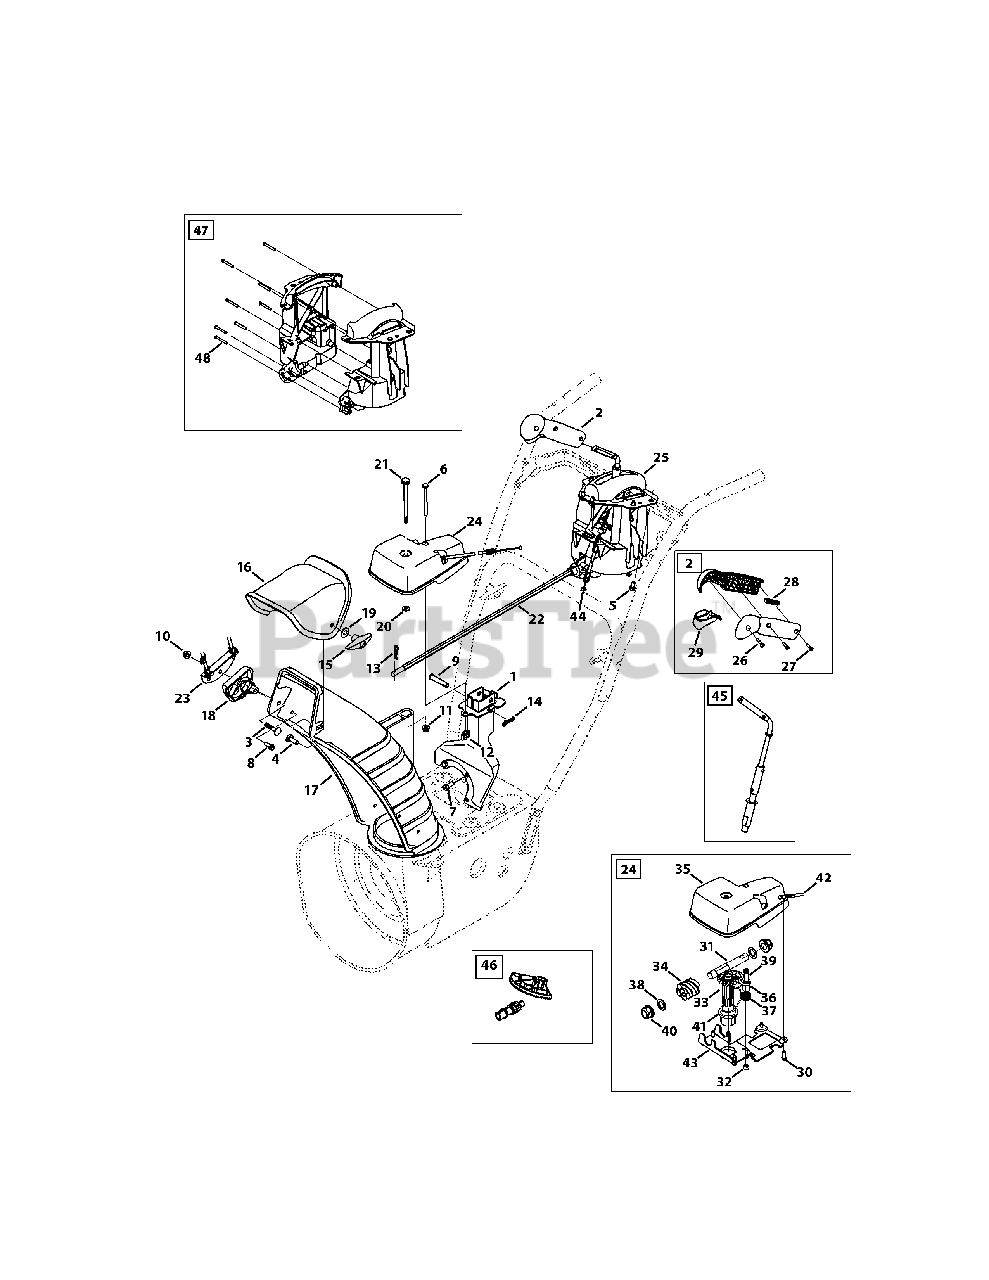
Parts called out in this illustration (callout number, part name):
1	Chute Support Bracket
2	Handle Assembly
3	Bolt, Carriage, 5/16-18 x 1.50
4	Bolt, Carrier, 5/16-18 x 1.00
5	Screw, HL, 1/4-15 x 0.50
6	Hex Head Screw, 1/4-20 x 3.00
7	Hex Head Screw, 5/16-24 x .750
8	Screw, HL, 1/4-15 x 0.750
9	Clevis Pin, 3/8 x 1.87
10	Nut, Flangelock, 5/16-18
11	Nut, Flangelock, 1/4-20
12	Wing Nut, 1/4-20
13	Internal Cotter Pin
14	Bow-Tie Cotter Pin
15	Star Knob, 5/16-18
16	Chute, Upper
17	Chute, Lower
18	Cable Guide, Chute Tilt
19	Washer, Flat, .349 x .879
20	Washer, Flat, .25 x .630
21	Screw, Shoulder, .312 x 3.5 x 1/4-20
22	Chute Rod, 3/8 Hex
23	Cable Bracket
24	Gearbox Assembly, Chute Rotation
25	Chute Control, 4-Way
26	Screw, #8 x 1.00
27	Screw, 8-32 x .750
28	Joystick Plug
29	Joystick Trigger
30	Screw, 12-16 x .75
31	Hex Shaft
32	Hexlock Nut, 1/4-28
33	Gear, 14 T
34	Worm
35	Gear Cover
36	Pawl Lock
37	Torsion Spring, .721 ID x .474
38	Washer, Flat, .625 x 1.0 x .067
39	Screw, Shoulder, .340 x .950 x 1/4-28
40	Hex Bearing
41	Flange Bearing
42	Cable Lock
43	Gear Bracket
44	4-Way Cable
44	4-Way Cable w/Clip
45	Shift Assembly
46	Gear Set Assembly
47	Handle Housing Assembly
48	Screw, #8-18 x 1.250
